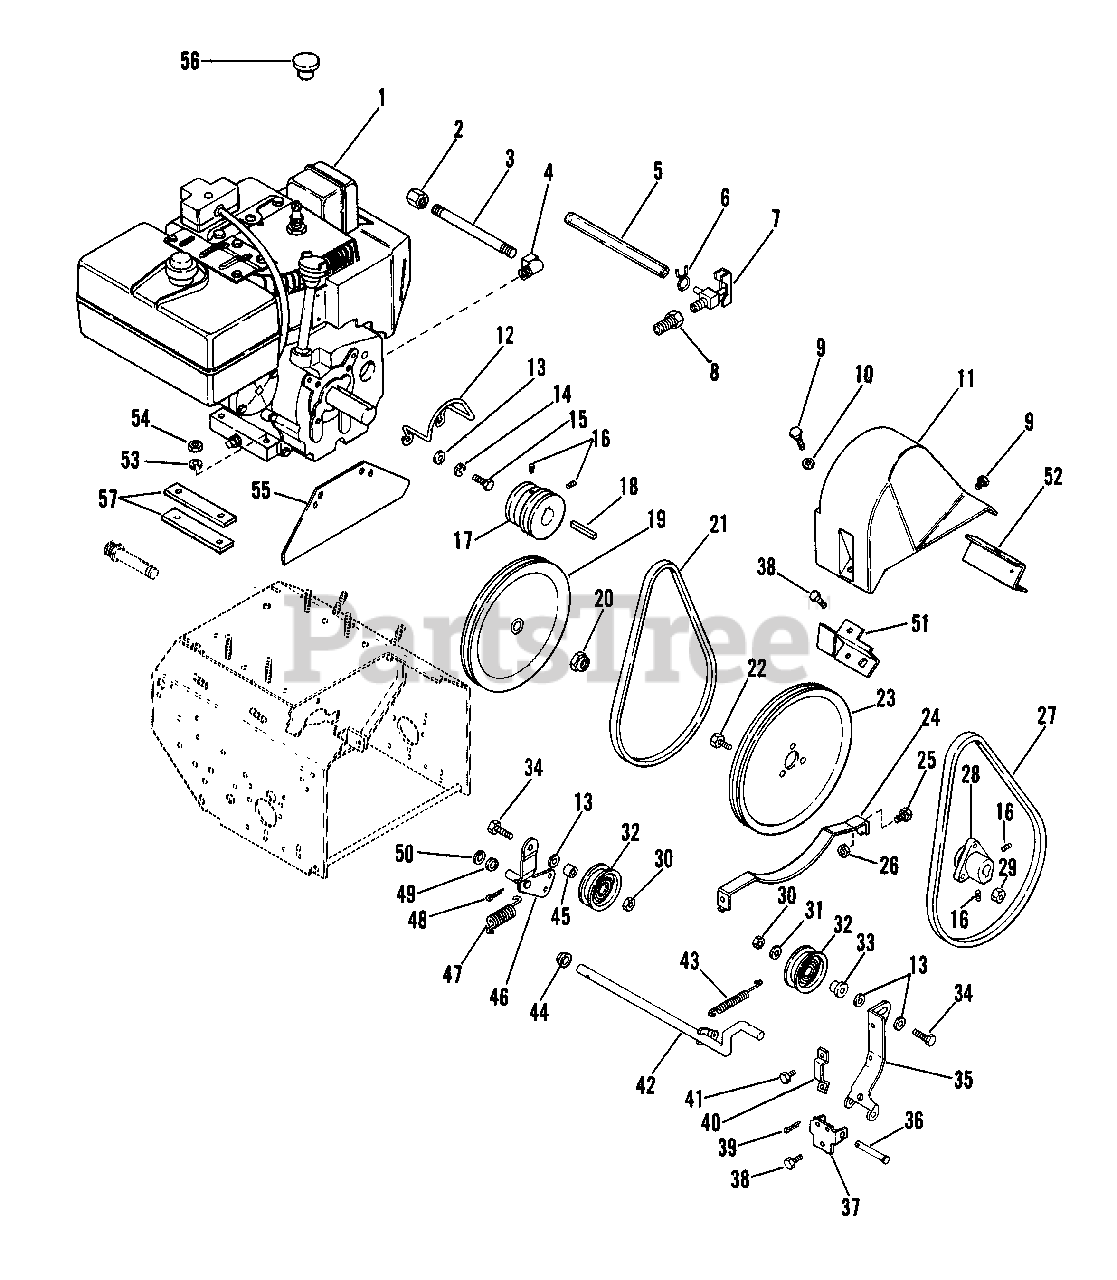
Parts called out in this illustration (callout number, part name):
1	5.0 HP LAUSON ENGINE
1	7HP TEC ENGINE
1	8.0 HP LAUSON ENGINE
1	8HP TEC ENGINE
1	10 HP TECUMSEH W/LIGHTING COIL
1	10 HP LAUSON ENGINE
1	ENGINE-10HP TEC 18 WATT ALTR
1	11 HP BRIGGS W/LIGHTING COIL -
1	11HP B&S ENGINE
1	ENGINE-OHSK 120 TEC W/18 WATT
2	HEX CAP
3	NIPPLE
4	STREET ELBOW
5	TUBE
6	HOSE CLAMP
7	DRAIN LOCK
8	BUSHING
9	SCR-TAP .25-20X.50 HWHPL
10	WSHR-FL-STL .268X.562X.046 PL
11	BELT COVER
12	BELT FINGER
13	WSHR-FL-STL .38X.875X.083 PL
14	WSHR-LK-EXT .313X.030 PL
15	BLT-HEX .31-24X.75 PL GR5
16	SCR-SET .32-18X.38 SKHCUPNL OH
17	ENGINE SHEAVE
17	SHEAVE, ENGINE
18	KEY-STR .25X1.75X.25
19	PLY-V 8.00 X 1.0 W/KEY CLARK
20	NUT-LK-NYL.625-18 PL
21	V-BELT, 3L-RAW EDGE
21	BELT,3L 33.00 RAW LAM C-L2089
22	BLT-SERRDHD SL .31-18X.87 PL
23	PLY-V 9.0 X 1.25 3BLT
24	BELT RETAINER
25	BLT-HEX .25-20X.50 PL GR2
26	NUT-LK-CTR .250-20 PL
27	V-BELT, 4L-RAW EDGE
29	NUT-FLG. .312-18 PL
30	NUT-LK .312-18 GR A PL
31	WSHR-FL-STL.312X.734X.065PL
32	IDLER
33	SPCR, BRG .315X.50X.688X.281
34	BLT-HEX .31-18X1.25 PL GR2
35	ARM, IDLER
36	PIN-CLEV .309X2.25
37	BRACKET
38	SCR-TAP .250-20X.37 HWH PL TR
39	PIN-COTR .09X.75 PL
40	RETURN CLIP
41	SCR-TAP 10-24X.375 HWH PL TR
42	ACTIVATING SHAFT
43	SG-TENS .047X.44X3.37 WLD 1.47
44	BSHG-FLG.500X.625X.312X.750NY
45	SPACER .50 X .32 X .42
46	IDLER ARM
47	SG-TENS .080X.73X3.06 WLD 20
48	PIN-COTR .12X1.0 PL
49	WSHR-FL-STL .382X.812X.023 PL
50	WAVE WASHER .406X.750X.063FH
51	R.H. SUPPORT
52	L.H. SUPPORT
53	WSHR-LK .312X.097 PL HVY
54	NUT-HEX .312-18
56	KNOB W/10-24 TAPPED METAL INSE
